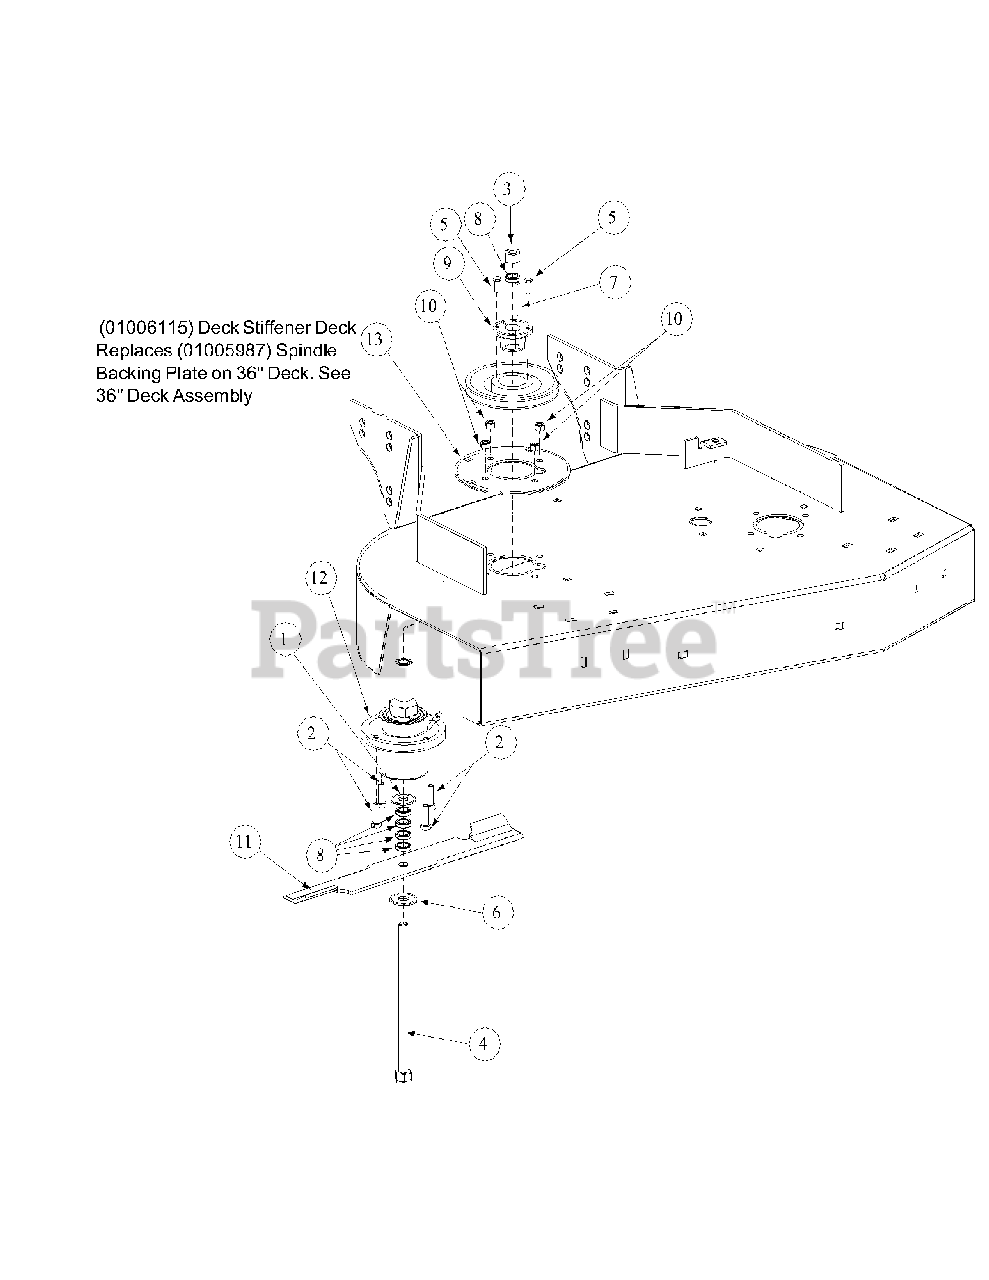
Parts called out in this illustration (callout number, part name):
1	Flat Washer, 1-1/2 x 5/8 x .05
2	Hex Cap Screw, 3/8-16 x 1-1/4
3	Hex Nut, 5/8-11
4	Hex Cap Screw, 5/8-11 x 9-1/2
5	Hex Cap Screw, 1/4-20, .75
6	Flat Washer, 5/8 Zinc
7	Key Stock, 1/4 x 1/4 x 2
8	Blade Spacer, 5/8 ID, 1/4 Thick
10	Lock Nut, 3/8-16
11	Blade 18"
12	Spindle Assembly
13	Plate, Spindle Backing
